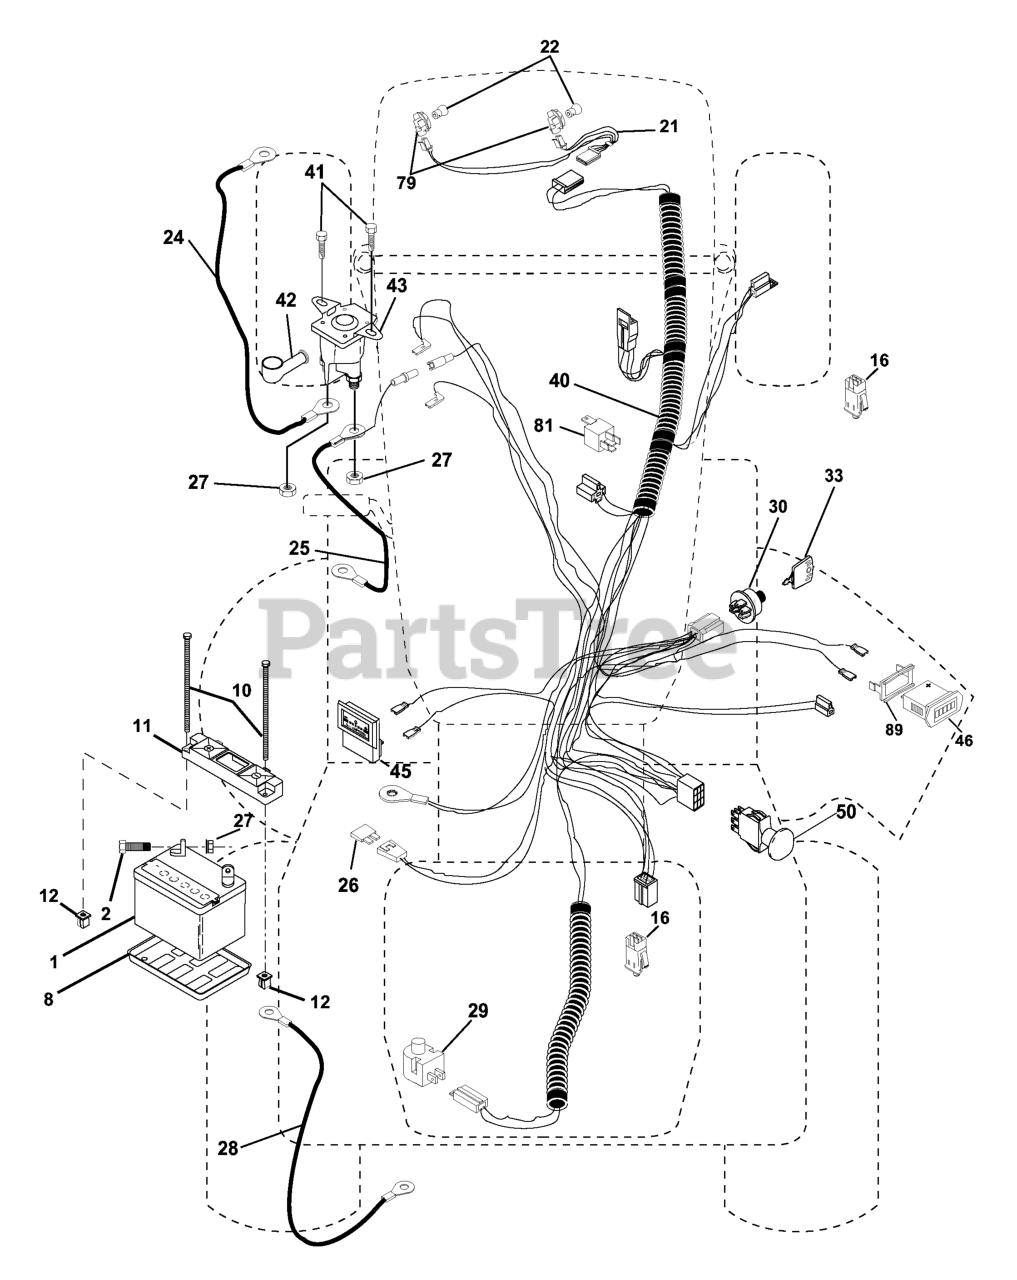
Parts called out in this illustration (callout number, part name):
1	BATTERY
2	BOLT.HEX.1/4.X.3/4.DICHROMATE
8	BATTERY TRAY T
10	BOLT 1/4-20 X 7.5
11	BATTERY HOLDDOWN FRONT MOUNT
12	NUT, PUSH NYLON 1/4" BATTERY
16	SWITCH INTERLOCK
21	HARNESS ASM LIGHT
24	HIGH SPEED GEAR
25	CABLE, BATTERY
27	NUT
28	CABLE, GROUND
29	PLUNGER SWITCH (COLOR:OLIVE)
30	IGNITION SWITCH
33	KEY MLD GEN DELTA
40	HARNESS, IGNITION
41	SCREW
42	TERMINAL COVER
43	SOLENOID
46	HOUR METER
50	RP.PTO.SWITCH.8 TERMINAL.BLACK
79	BULBHOLDER ASM
81	RELAY.ASSY.T
89	BRACKET SNAP-IN HOURMETER
